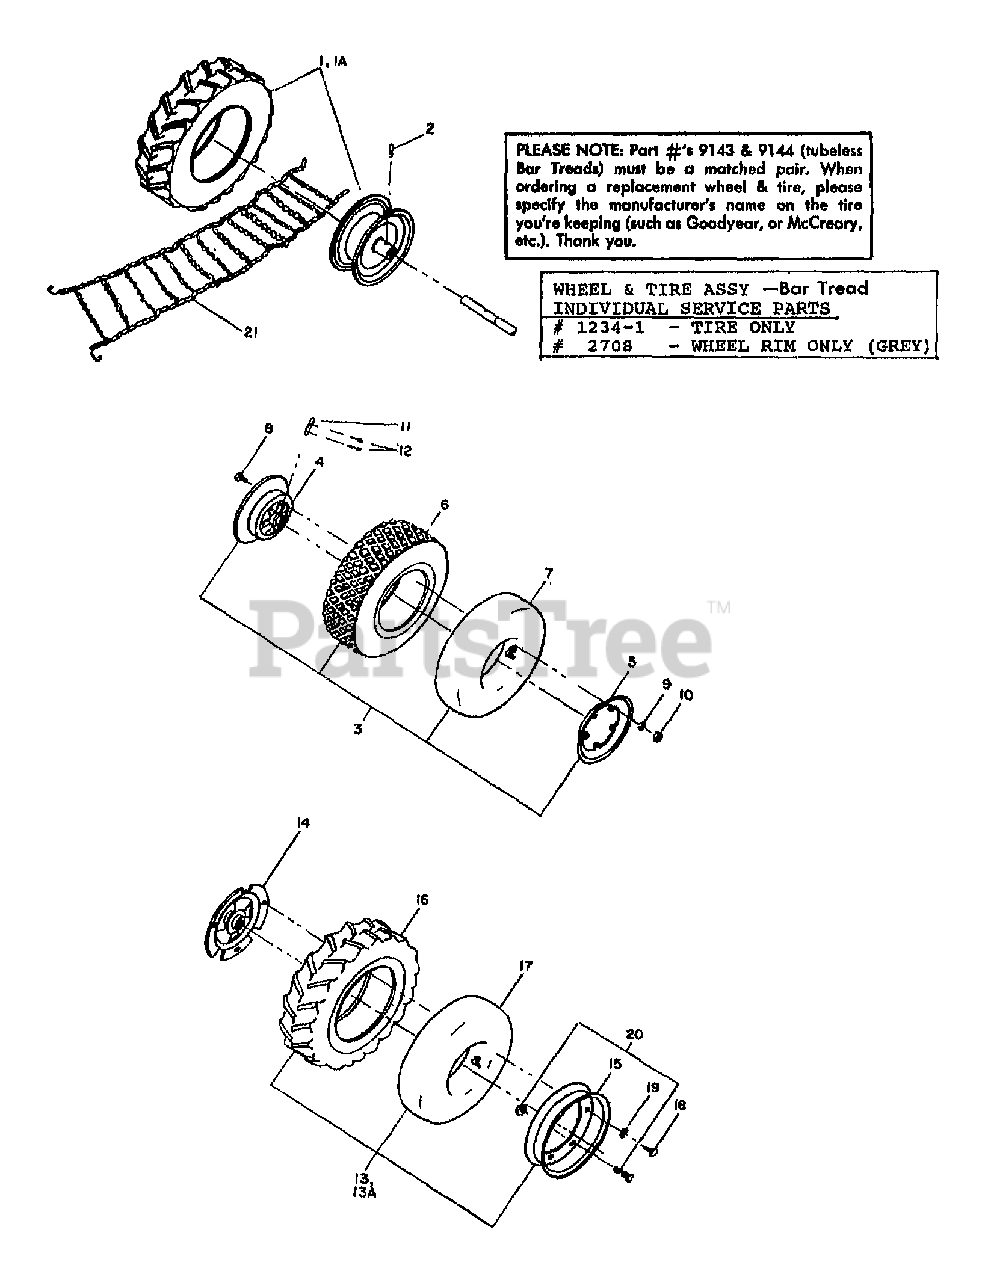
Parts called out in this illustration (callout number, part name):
1	TIRE-RT BT GARDEN TRAC
1A	TIRE-LT BT GARDEN TRAC
2	PIN-SPIROL .313 X 1.5
3	4X7TIRE/TUBE
4	HUB-4X7
5	WHEEL RIM
6	TIRE 4X7
7	TUBE-4X7
8	SCR-HH 3/8-16X1.25
9	WASHER-LK .375 @ DEPL
10	NUT-HEX 3/8-16 ZP
11	KIT-NUT/BOLT PIN WHL/SHAFT
12	PIN-COTTER .094X1.0
13	ASSM-WHEEL 4X8 BTT
13A	ASSM-RT WHL BTT
14	HUB-WHEEL MACH
15	RIMS W/HDW (1648)
16	TIRE-BTT 4.80/4.00X8.00
17	TUBE-INNER BT (4 X 8)
18	SCR-HH 3/8-16X.75 G5 ZP
19	WASHER-LK .375 @ DEPL
20	STUD & NUT
21	CHAINS-HORSE TILLER
